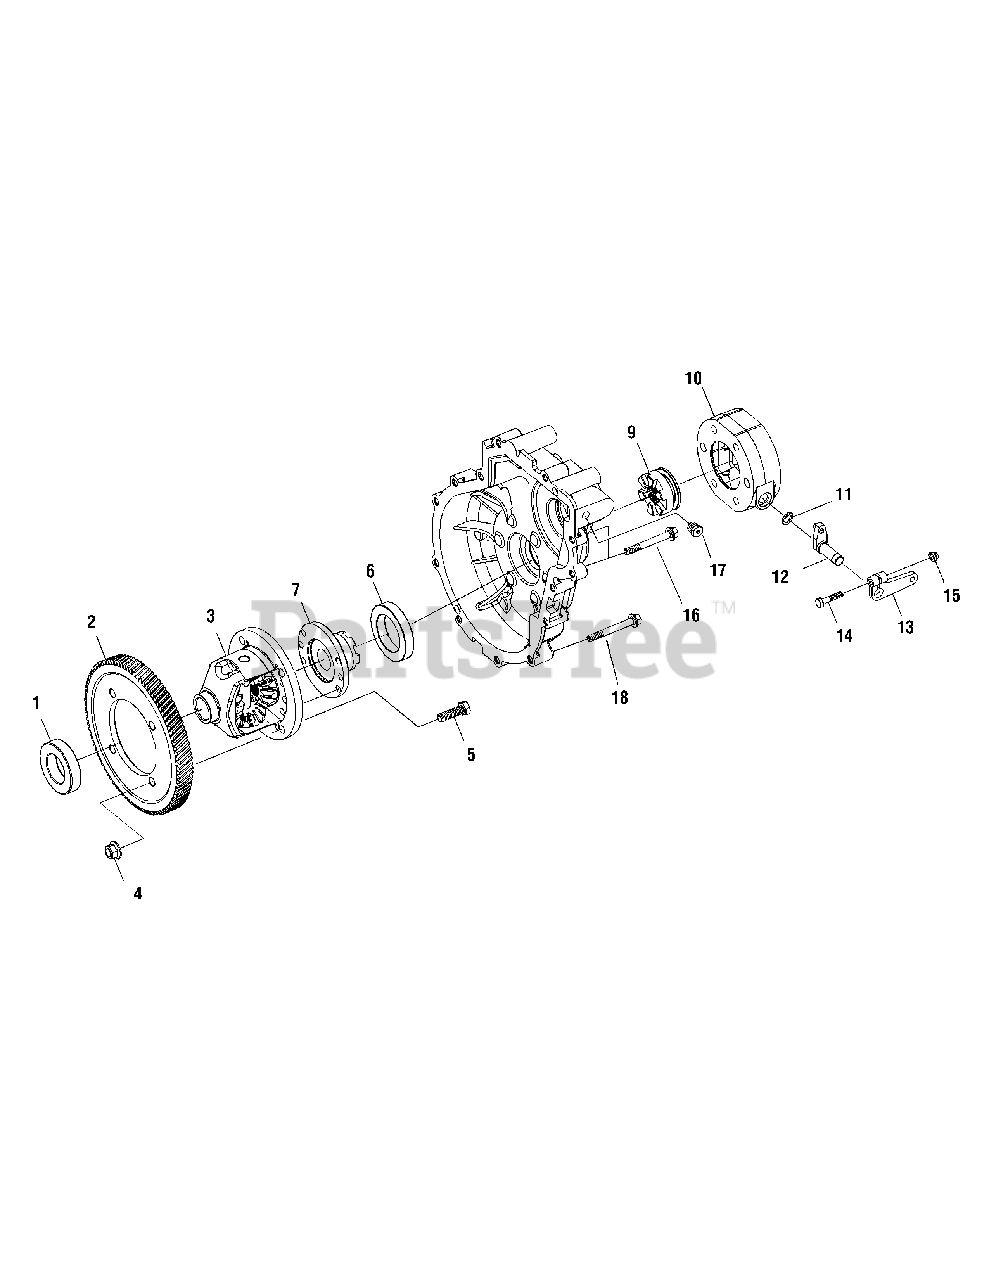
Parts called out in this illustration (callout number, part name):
1	Bearing, Ball
2	Gear, Helical (Ring)
3	Assembly, Differential
6	Bearing, Ball
7	Flange, Half, Differential
8	Screw, Socket Head
9	Gear, Clutch Differential Lock
10	Housing, Differential Lock
12	Assembly, Shift Shaft
13	Lever, Actuating
14	Screw, Hex Head
16	Screw, Flange Head
18	Screw, Flange Head
